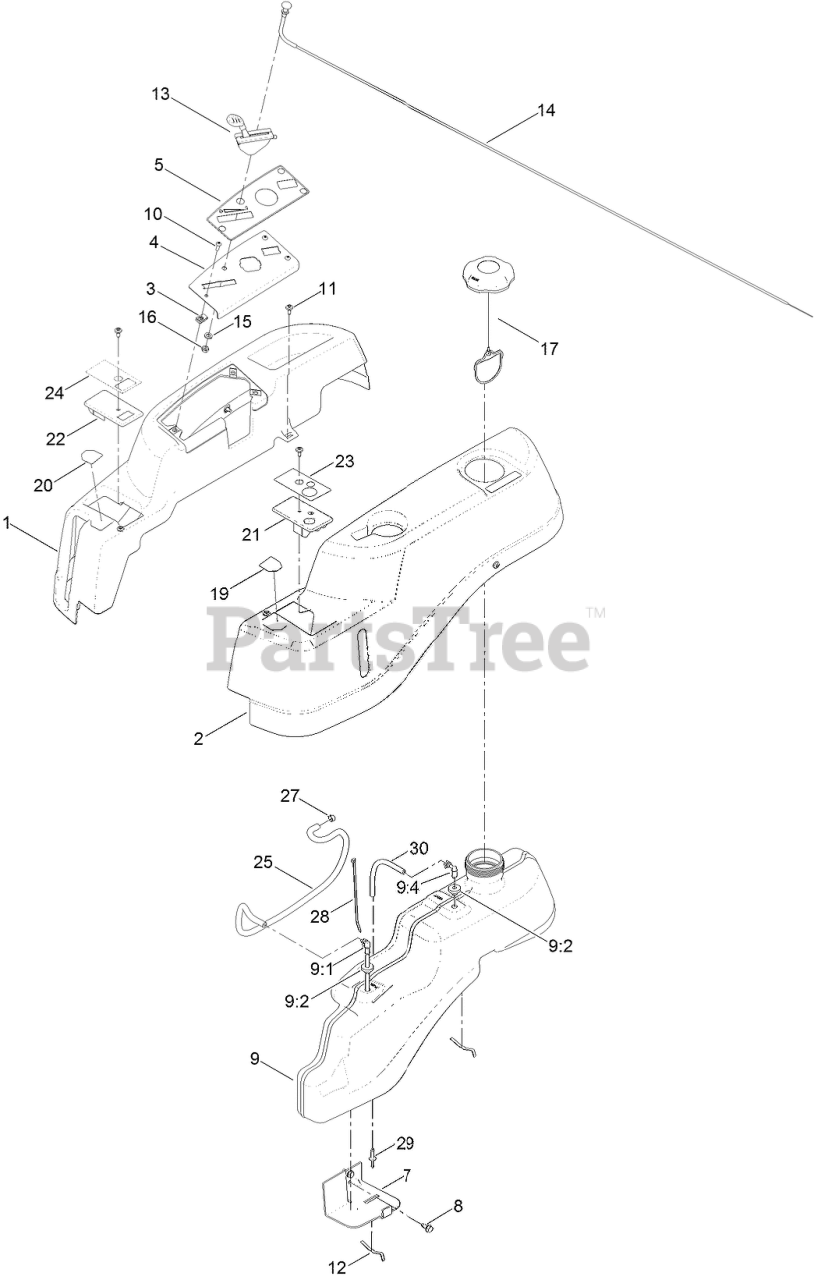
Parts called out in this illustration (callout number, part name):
1	POD-RH
2	POD-LH
4	PLATE-CONTROL
5	DECAL-PANEL, CONTROL
7	SUPPORT-TANK, FRONT
8	SCREW-HWHTF
9	FUEL TANK ASM
9:1	CONNECTOR-ELBOW, 90 DEG
9:2	BUSHING
9:4	FITTING-PLASTIC
10	SCREW-PRH
11	SCREW-SHOULDER
12	SPRING
13	CABLE-THROTTLE
14	CABLE-CHOKE
15	WASHER-LOCK
16	NUT-HJ
17	CAP-FUEL, RATCHETING
19	DECAL-NMIR
20	DECAL-CONTROL, PEDAL
21	COVER-LH
22	COVER-RH
23	DECAL-KEYCHOICE
24	DECAL-BRAKE, PARKING
25	HOSE-FUEL
27	CLAMP-HOSE
28	TIE-CABLE
29	ADAPTOR-ORIFICE
30	HOSE-FUEL
